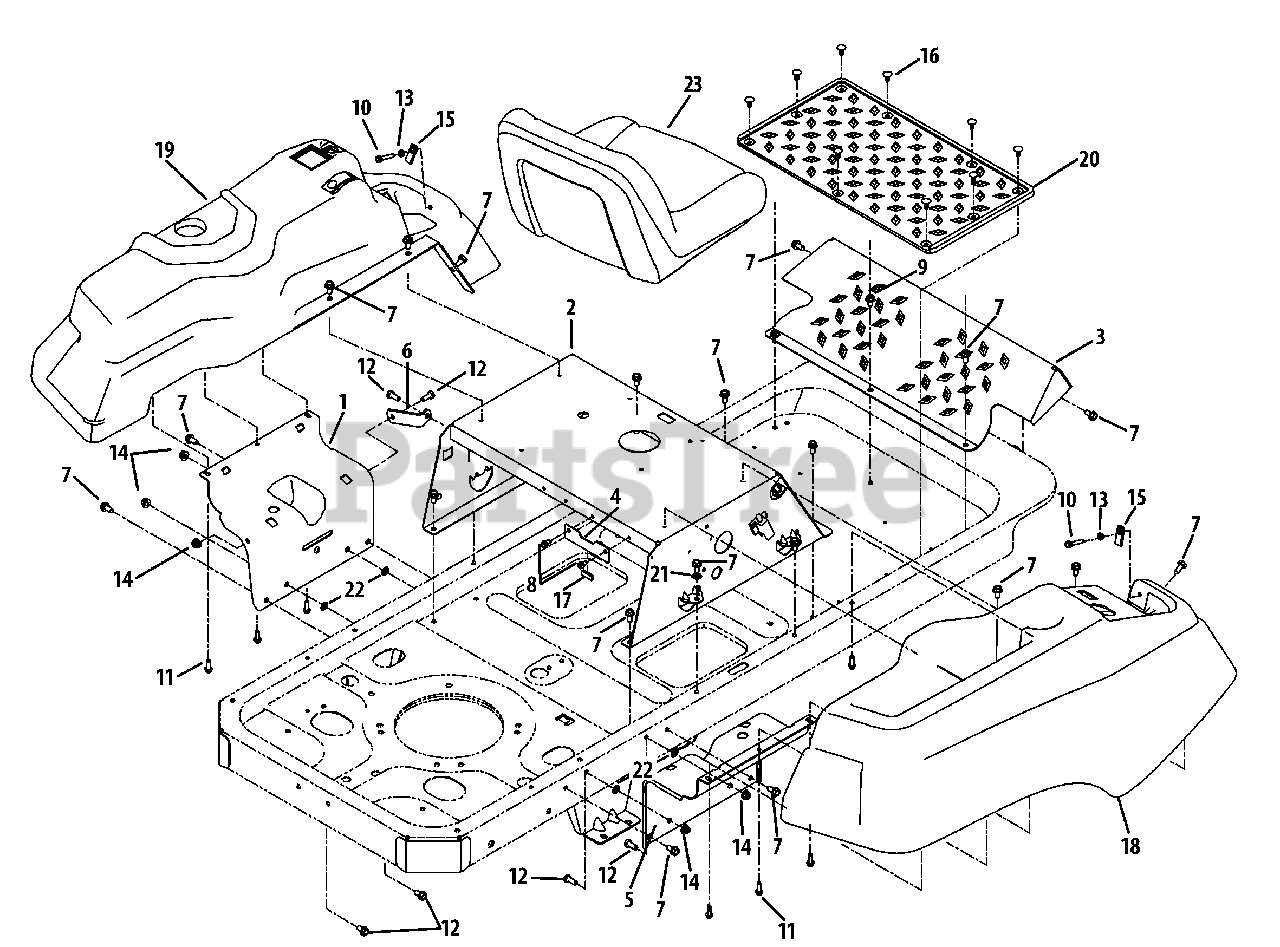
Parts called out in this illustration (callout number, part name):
1	Console Bracket Assembly
2	Seat Frame Assembly
3	Foot Rest Bracket
4	Battery Hold-Down Bracket
5	Console Mount Bracket
6	Fuel Tank Support Bracket
7	Hex Washer Screw, 5/16-18 x .750
8	Hex Washer Screw, 1/4-20 x .500
9	Hex Washer Screw, 5/16-18 x .625
10	Hex Washer Screw, 1/4-20 x 1.500
11	Hex Washer Screw, 1/4-15 x .750
12	Hex Screw, 5/16-18 x .75 (TB)
13	Jam Nut, 1/4-20
14	Flange Lock Nut, 5/16-18
15	Speed Nut, 1/4-20
16	Ratchet Clip
17	Trim Strip
18	RH Console
19	LH Console
20	Foot Pad
21	Lock Washer, 3/8
22	Speed Nut, .3125
23	High-Back Seat Arm
